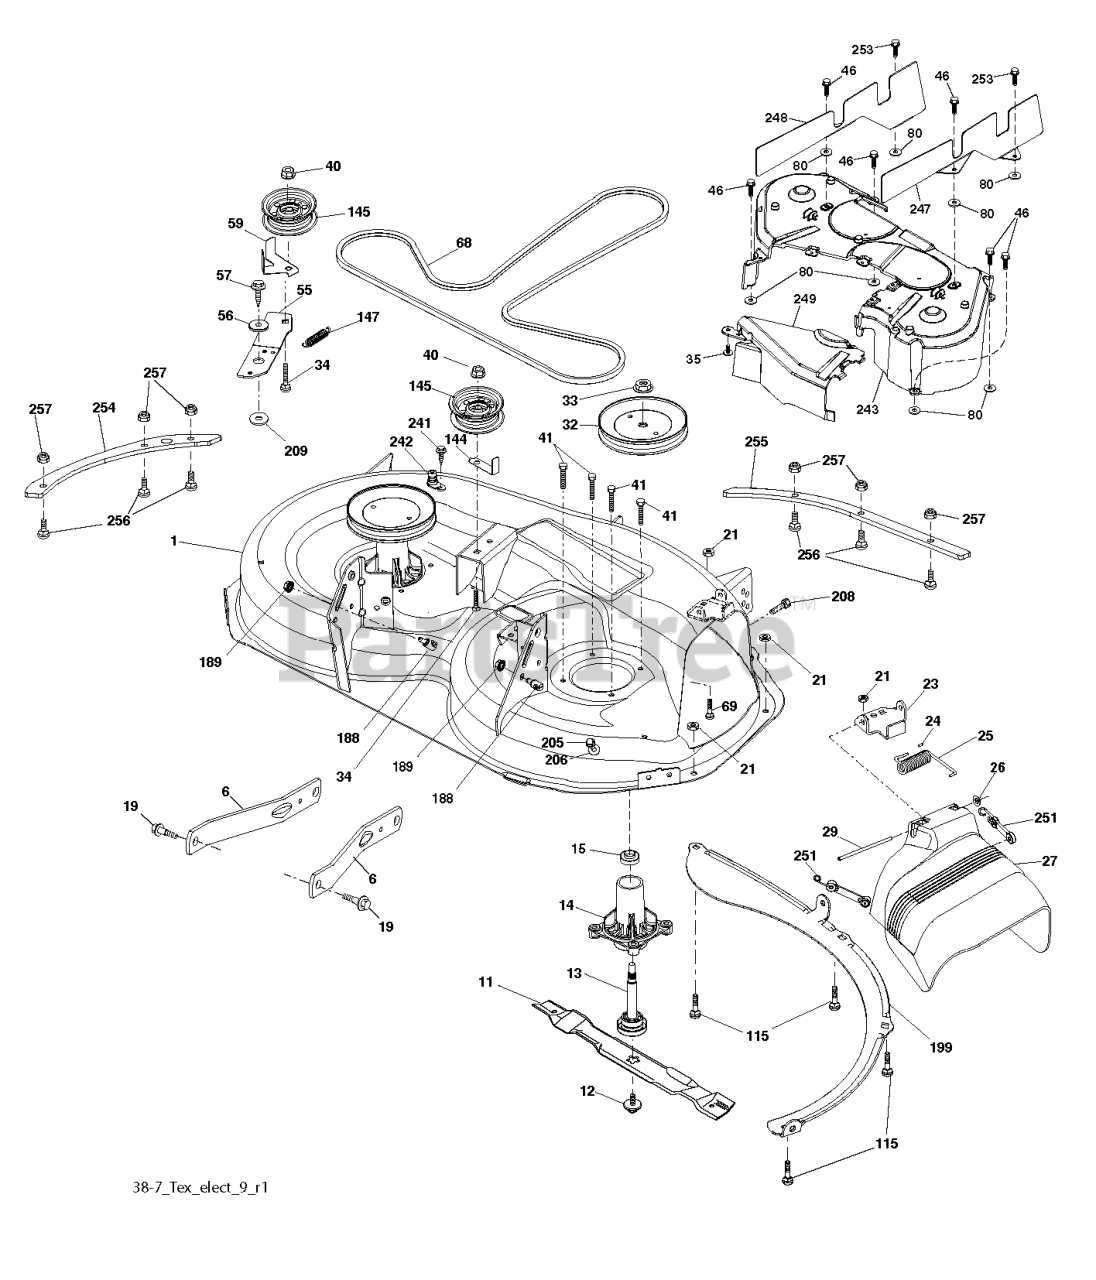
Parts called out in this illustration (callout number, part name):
1	DECK.38.WELDMENT.GREY
6	ARM.SUSPENSION.MOWER.R
8	BOLT.WASHER.ASM.7/16-2
11	BLADE 38" PREMIUM
13	SHAFT.ASM.MDRL.N/GREASE.38
14	RP.HOUSING.MANDREL.4PT.
19	BOLT.SHOULDER
21	LOCKNUT
23	BRKT.DEFLECTOR.38"2005+
24	CAP-SLEEVE LT
25	SPRING.TORSION.DEFLECT
26	NUT PUSH M
27	SHIELD ASM.DFLCTR MWR.38-7"BLK
29	ROD.HINGE
31	WASHER.SPACER.MANDREL
32	PULLEY MANDREL
33	NUT.FLANGE.LOCK.TOP
34	BOLT.3/8-16X1.50
35	FASTENER.XMAS.TREE
40	NUT LOCK FLG 3/8-16 UNC
41	BOLT.HEX.WASHR.HED.313-18X1.19
46	SCREW.1/4-20X5/8
55	IDLER.ARM
56	SPACER.RETAINER
57	SCREW 3/8-16X1
59	GUARD, BELT
68	BELT BELT 38' ELEC. DECK
69	BOLT
80	PALNUT 1/4
115	BOLT.CARR.5/16-18X5/8.SHORT
144	KEEPER BELT
145	PULLEY.IDLER.48"PRIMARY
147	SPRING.MOWER.DRIVE.ELECTRIC
188	STUD.FASTNER.W/ANTI-ROTATE
189	NUT LOCK HEX FLANGE 5/16-18
199	BAFFLE.VORTEX.FRONT.38"
205	SCREW
206	WASHER
208	SCREW 3/8-16X1/2
209	WASHER 12/32X2X10GA
241	SCREW.TT.#10-32X.5.3/8.FLANGE
242	PORT.WASHOUT
243	COVER DECK 38-7
247	SHIELD RIGHT
248	SHIELD LEFT
249	COVER CABLE CLUTCH
251	ELASTIC STRAP KIT
253	SCREW
